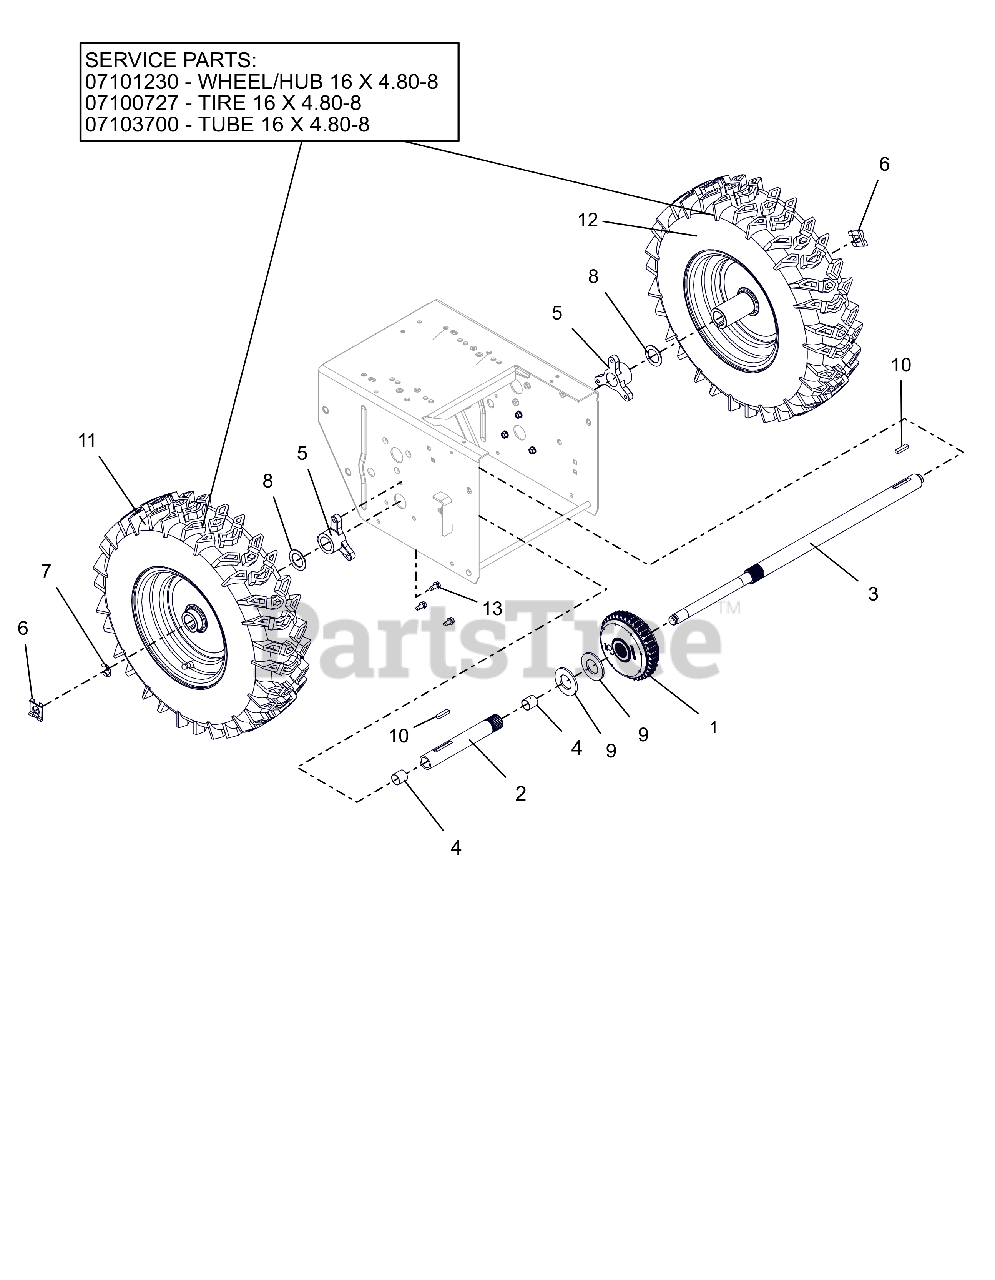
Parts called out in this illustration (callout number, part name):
1	DIFFERENTIAL, AUTOMATIC
2	AXLE, SHORT - W/BUSHINGS
3	AXLE,LONG-DELUXE AUTO DIFF
4	BSHG-SLV .706X.764X.75 BRZ
5	BUSHING, AXLE
6	CLIP, SNAP .625 DIA
7	RG-RTNG-EXT .625X.042
8	WSHR, FLT 1.010X1.505X.062 ZCC
9	WSHR, FLT 1.062X2.000X.134 ZCC
10	KEY-RECT .25X.188X1.00
11	TIRE/WHEEL,RH 16X4.8-8 DIFF T2
11-12	HUB, WHEEL-16X4.8-8
11-12	TIRE, 4.80-8 K478
11-12	TUBE
12	TIRE/WHEEL,LH 16X4.8-8 DIFF T2
13	SCR-TAP .25-20X.50 HWH ZCC
